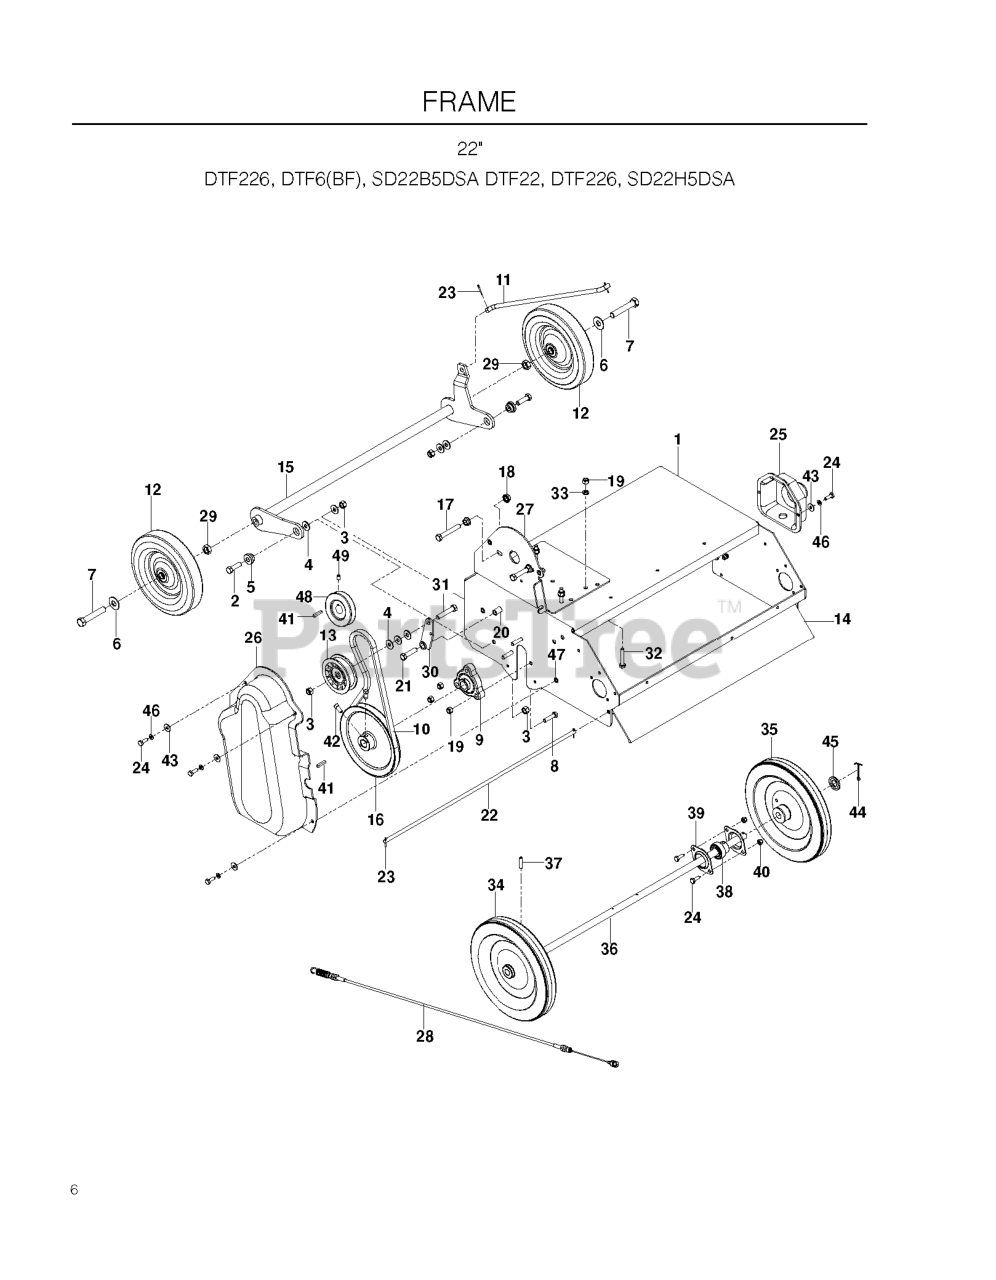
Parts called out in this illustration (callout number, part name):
1	WLDMT, BODY - ORANGE DT22
2	HCS 3/8C X 1 1/4 GR5
3	NUT 3/8-16 NYLOC
4	WASHER 5/16 FLAT
5	BUSHING RAKE
6	WASHER 1/2 FLAT
7	HCS 1/2C X 2 3/4
8	HCS 5/16C X 1 1/4
9	BEARING, FLANGED
10	BELT, DRIVE RAKE/SLICER DFS
12	WHEEL 8 X 1 3/4 RAKE
13	PULLEY, IDLER RAKE & ZTR
15	FRONT AXLE
16	PULLEY, MAIN SHAFT
17	HCS 3/8C X 2 1/2
18	NUT 3/8C WHIZ
19	NUT 5/16 NYLOC
20	BEARING, ONLITE RAKE/DT
21	HCS 3/8C X 1 1/2
23	COTTER PIN 3/32 X 3/4
24	HCS 1/4C X 3/4 HCS
25	SHAFT GUARD
26	BELT GUARD
27	BACKING PLATE ORANGE
28	CABLE POWER RAKE
29	NUT 1/2 HEX JAM
30	IDLER ARM - ORANGE
31	HCS 3/8C X 2
32	HCS 5/16C X 1 3/4
33	WASHER.LOCK.HVY.HLCL.SPR.5/16
34	WHEEL 10 X 1 3/4
35	WHEEL 10 X 1 3/4
36	AXLE, REAR
37	PIN ROLL 1/4 X 1-1/8
38	BEARING - 5/8" W/COLLAR
39	FLANGE BEARING ZINC PLATED
40	NUT.1/4-20.HEX.NYLOC.ZD
41	KEY, 3/16 SQUARE
42	SCREW 5/16C X 5/8 SQ HEAD
43	WASHER 1/4 FLAT
44	COTTER PIN
45	WASHER 5/8 FLAT
46	LOCKWASHER 1/4"
47	KNURLED INSERT
48	ENGINE PULLEY - 5.5 HP
49	SET SCREW 5/16 NYLOC
